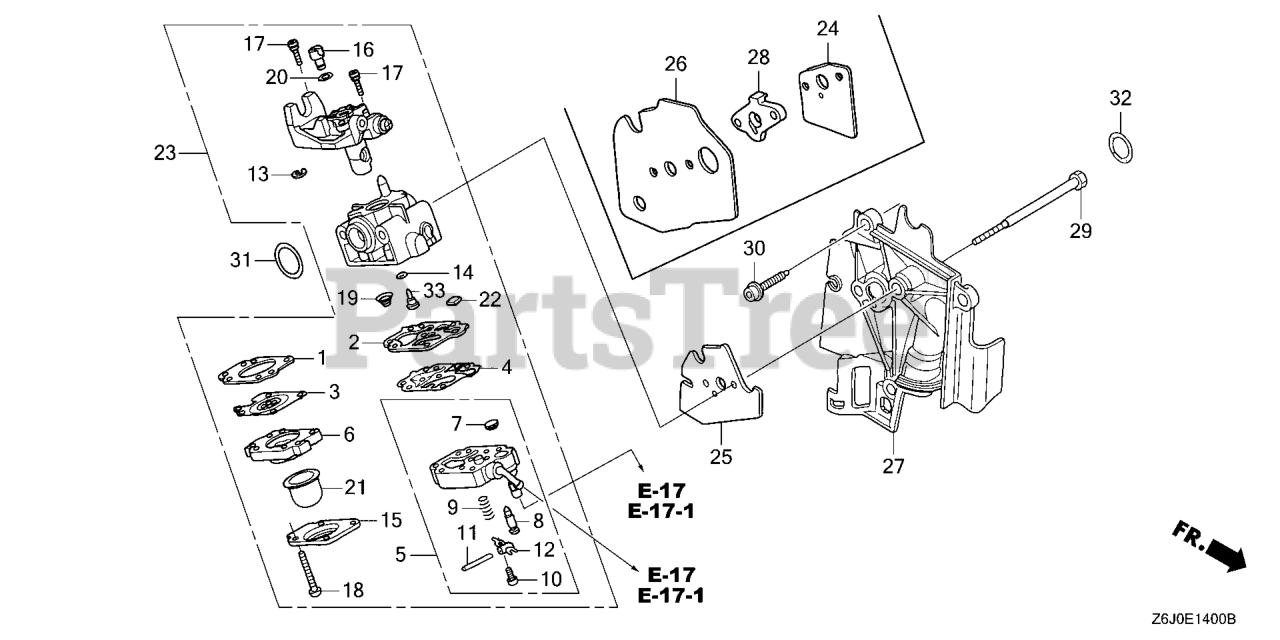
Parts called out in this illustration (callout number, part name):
1	GASKET, METERING DIAPHRAGM
2	GASKET, PUMP (CARBURETOR NO.)
3	DIAPHRAGM ASSY., METERING
4	DIAPHRAGM, PUMP
5	BODY ASSY., PUMP
6	BODY ASSY., AIR PURGE
7	SCREEN, INLET (CARBURETOR NO.)
8	VALVE, INLET NEEDLE
9	SPRING, METERING LEVER
10	SCREW, METERING LEVER PIN
11	PIN, METERING LEVER
12	LEVER, METERING
13	RING, RETAINING
15	COVER, PRIMER PUMP
17	SCREW, THROTTLE COLLAR
18	SCREW, PUMP COVER
19	SPRING, PUMP
21	PUMP, PRIMER
22	FILTER, FUEL INLET (CARBURETOR NO.)
23	CARBURETOR ASSY. (WYB 47A)
24	GASKET, CARBURETOR
26	GASKET, SHROUD
28	SPACER, SHROUD
29	BOLT (5X58)
30	BOLT, SOCKET (5X16)
31	O-RING (14.8X2.4)
32	O-RING (12.3X2.4) (CARBURETOR NO.)
33	JET (#33) (CARBURETOR NO.)
33	JET (#34) (CARBURETOR NO.)
33	JET (#35) (CARBURETOR NO.)
